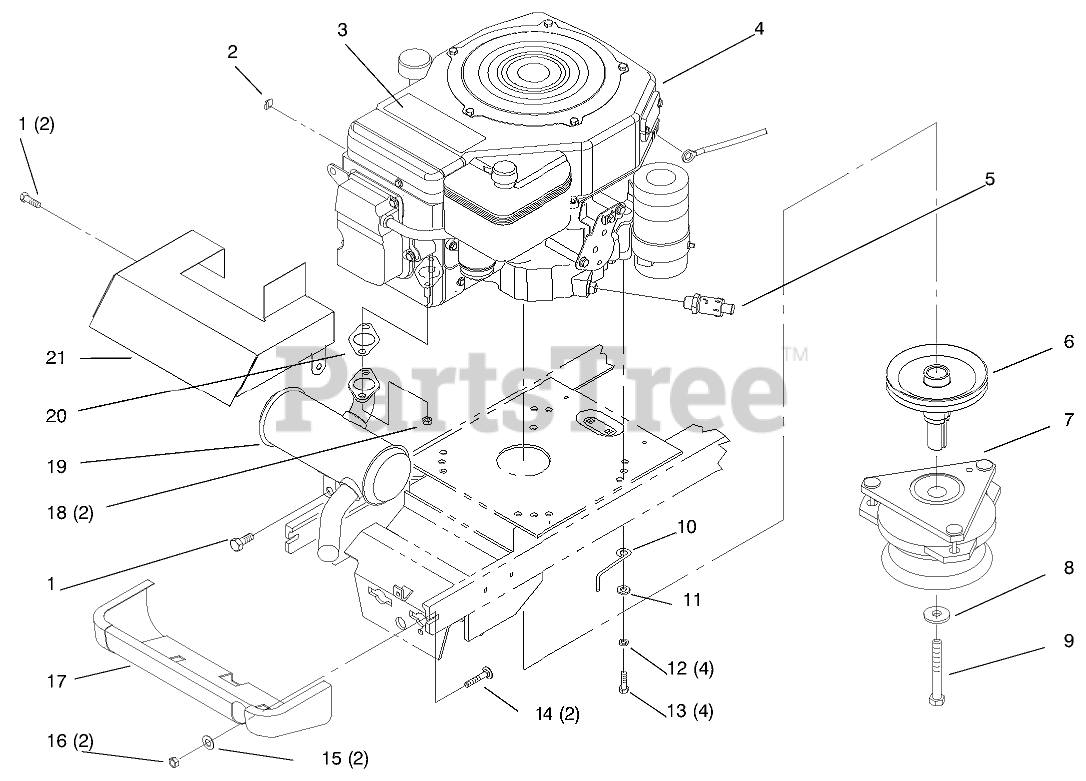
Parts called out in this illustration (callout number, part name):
1	SCREW-HWHTF
2	CLIP-RETAINER, WIRE
3	DECAL - LOGO
4	Engine-Kohler (Only On: 72046)
4	Engine-Kohler (Only On: 72064)
5	VALVE-DRAIN, OIL
6	PULLEY-ENGINE
7	Clutch-PTO (Only On: 72064)
7	Clutch-Electric PTO (Only On: 72046)
8	WASHER
9	SCREW-HH
12	WASHER-LOCK
13	SCREW-CAP, HH
14	BOLT-CARR
15	WASHER-FLAT
16	NUT-LOCK, NI
17	Shield-Muffler
18	NUT-HF
19	Muffler
20	Gasket-Exhaust
21	SHIELD-MUFFLER
